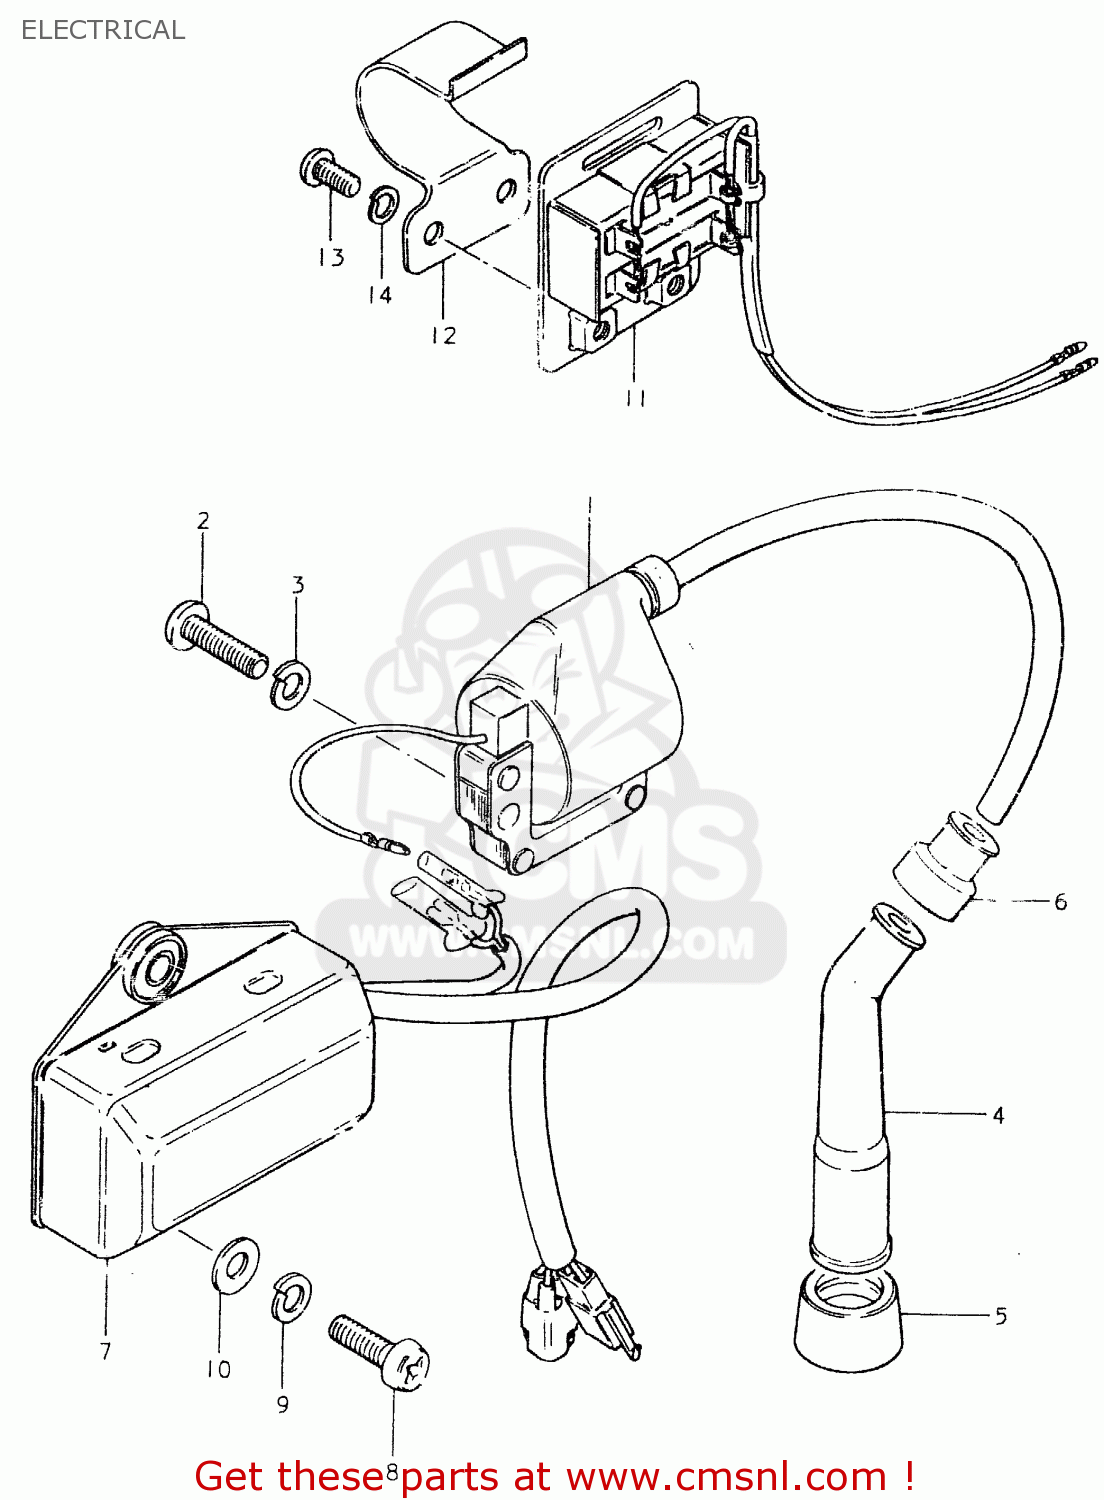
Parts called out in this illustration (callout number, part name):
1	COIL ASSEMBLY,IGNITION
2	SCREW
3	LOCK WASHER
4	CAP ASSY,SPARK PLUG
5	SEAL,SPARK PLUG
6	SEAL,SPARK PLU
7	CDI UNIT
8	SCREW
9	LOCK WASHER
10	WASHER
11	RESISTOR ASSY, CITY LAMP
12	CLAMP
13	SCREW 6X12
14	LOCK WASHER
